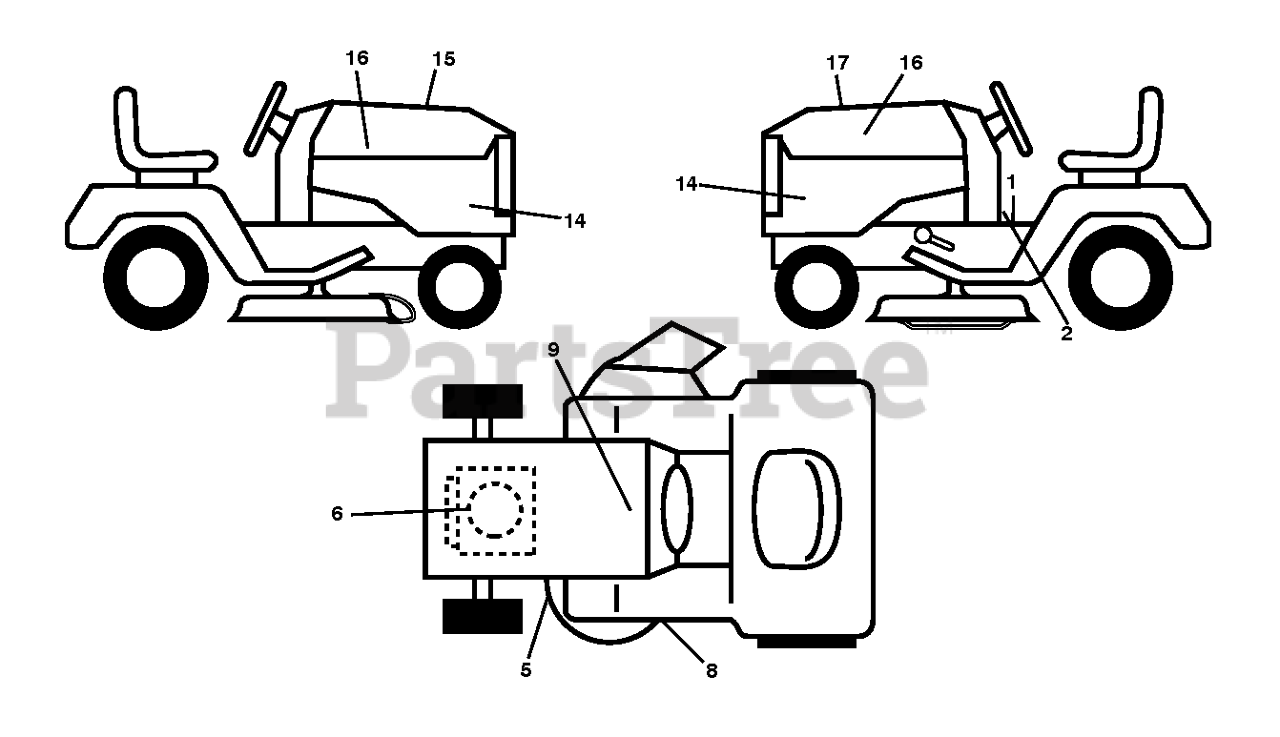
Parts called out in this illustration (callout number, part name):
1	DECAL.FENDER.WARNING
2	DECAL, WARNING SPARK ARRESTOR
3	DECAL.WARN.KEEP.HAND.AWAY
5	DECAL.MOWER
6	DECAL.ENG.BS.23HP.XRD.TWIN
8	DECAL.MOWER.SCH.48/54
9	DECAL BTRY SYMBOLS
14	DECAL.SDPNL.YTH2348.BS.SET.HUS
15	DECAL.WARNING.CUST.RESP.E85.
16	RP.DECAL.BADGE.170MM.TEXTLOGO
17	DECAL.RPL.BSM44.INTK.TLW.48.K4
